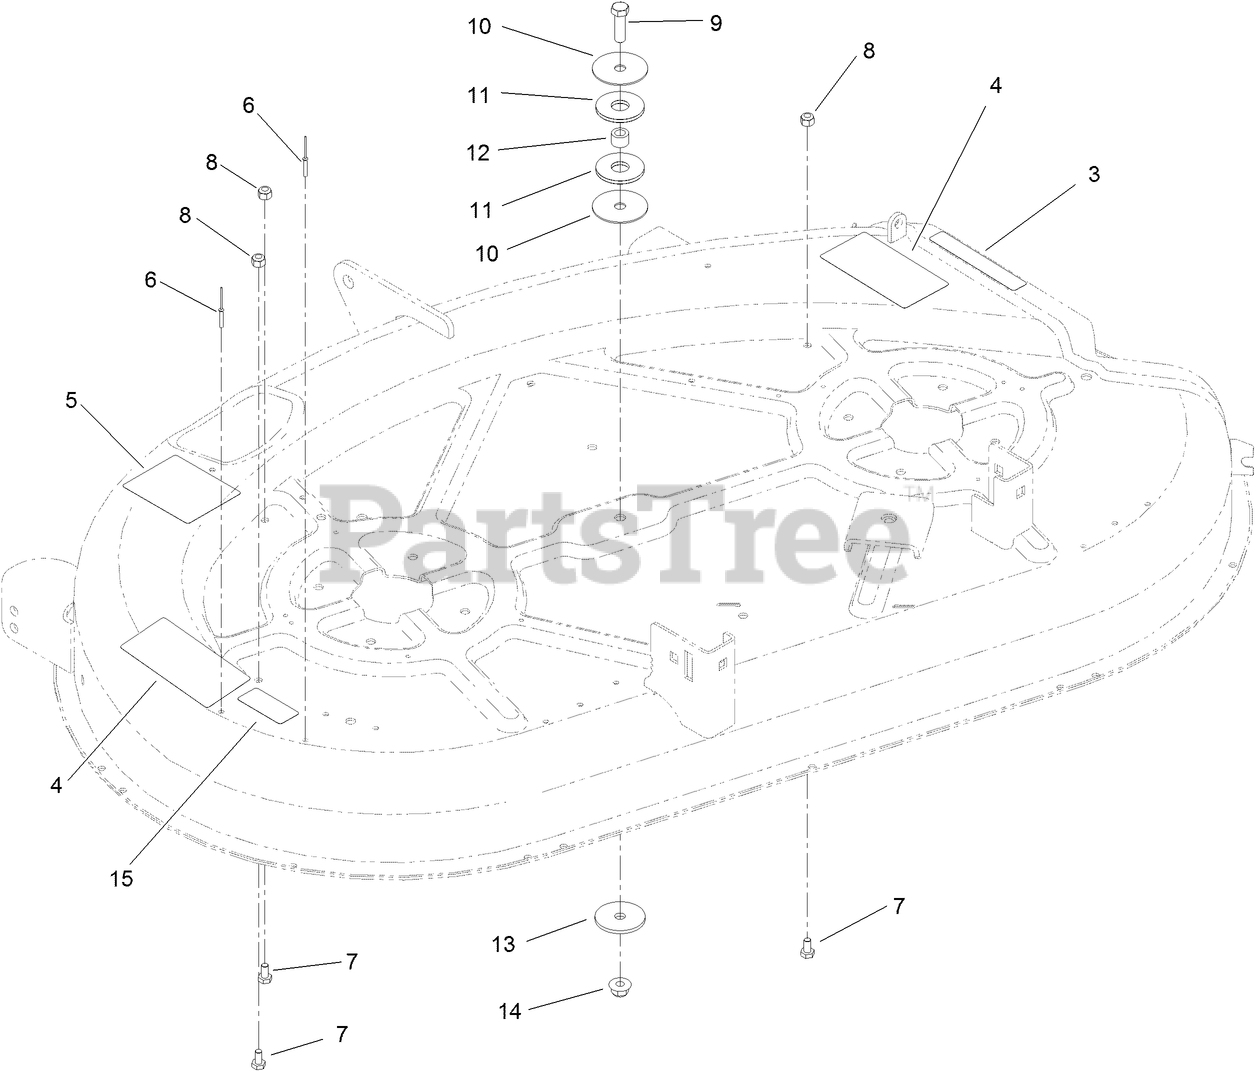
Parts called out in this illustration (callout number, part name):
3	DECAL-DANGER
4	DECAL-DANGER, DECK
5	DECAL-ROUTING, BELT
6	RIVET-BLIND
7	SCREW-HH
8	NUT-LOCK, NI
9	SCREW-HH
10	WASHER
11	WASHER-FRICTION, COMPOSITE
12	SPACER
13	WASHER-REBOUND
14	NUT-HF, NI
15	DECAL-SERVICE DECK
